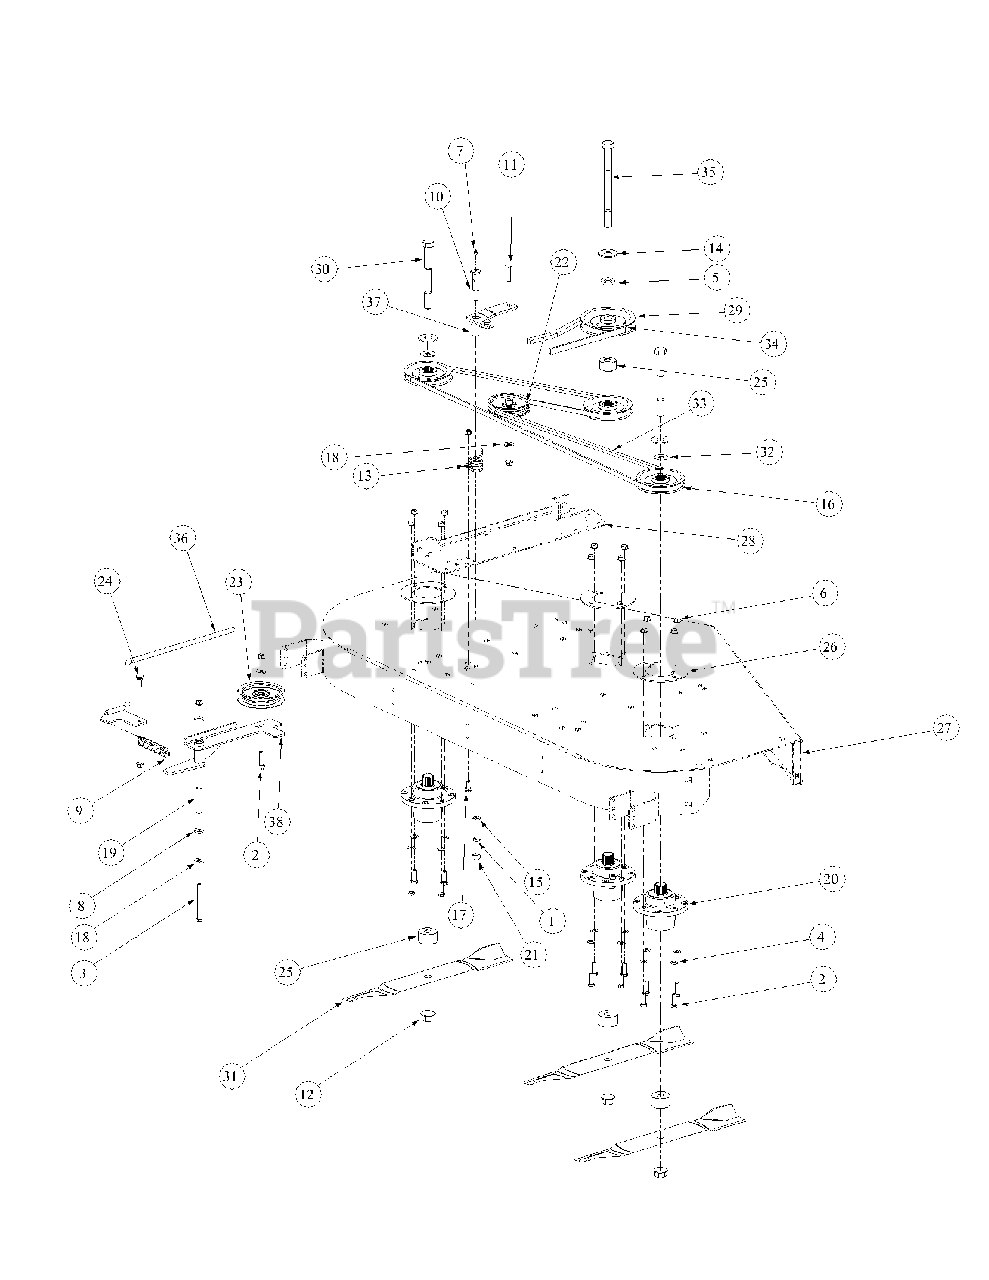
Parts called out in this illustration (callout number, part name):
1	Lock Washer, 7/16
2	Hex Cap Screw, 3/8-16 x 1-1/2
3	Hex Cap Screw, 3/8-16, 3.75
4	Flat Washer, 3/8
5	Caster Spacer
6	Flange Lock Hex Nut, 3/8-16
7	Grease Fitting, 1/4-28 x 3/16
8	Idler Washer
9	Extension Spring, 1.0 x OD x 5.125
10	Shoulder Screw, 7/16-14
11	Hex Carriage Screw, 3/8-16, 1.75
12	Flange Hex Nut, 3/4-16
13	Torsion Idler Spring
14	Flat Washer, .781 ID 2.00 OD, .105
15	Flat Washer, .469 ID, .875 OD, .105
16	V-Pulley, 4.65 OD
17	Carriage Bolt, 3/8-16 x 1
18	Flat Washer, .406 ID, 1.0 OD, .105
19	Spacer, .39 ID x .625 OD x 2.75
20	Aluminum Spindle Assembly
21	Hex Nut, 7/16-14
22	Flat Pulley
23	Idler Pulley, 4.06 OD
24	Shoulder Screw, .50 x .27 Lg., 3/8-16
25	Spacer, .760 ID x 2.00 OD x 1.1
26	Aluminum Spindle Support Plate
27	60 Deck Assembly
28	Left Hand Mount Deck Bracket Assembly
29	V-Pulley, 5.774 OD
30	Hex Cap Screw, 3/4-16, 7.00
31	Hi-Lift Blade, 21.0, 0.756 ID
32	Spacer .812 ID x .268 LG
33	V-Belt, A Section x 122.3
34	V-Belt, B Section x 91.2
35	Hex Cap Screw, 3/4-16, 9.00
36	Spring Tension Rod Assembly
37	Idler Arm Assembly, Deck Spindle
37	Bearing Sleeve
38	Idler Arm Assembly, Flat Top Bearing
38	Bearing Sleeve
